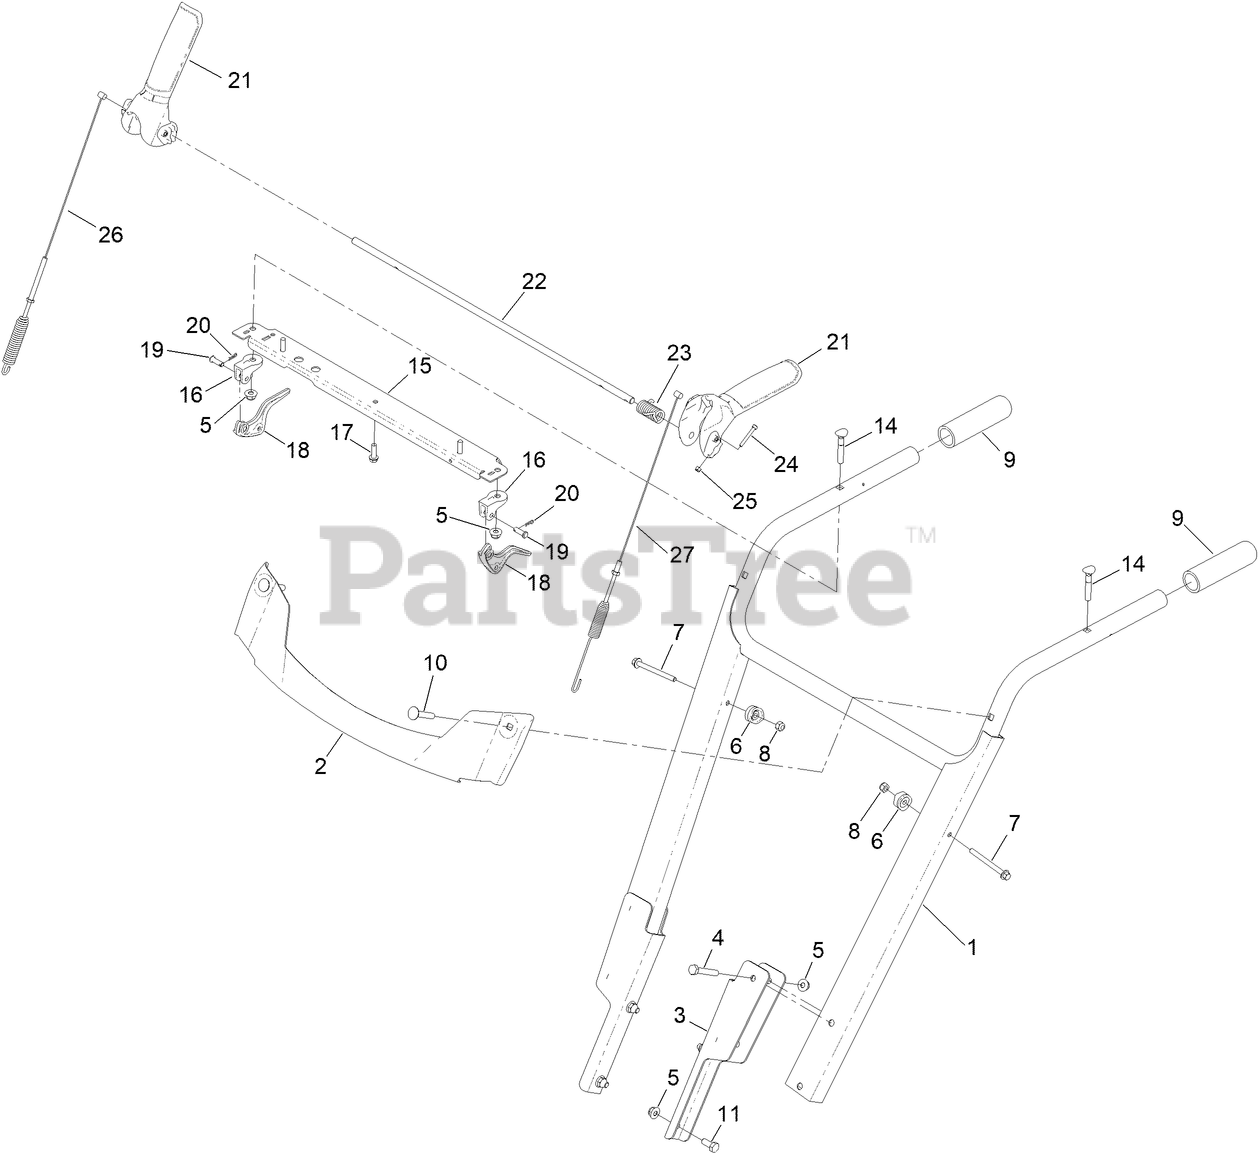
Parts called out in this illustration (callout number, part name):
1	HD HANDLE ASM
2	TRIM-METAL, HD
3	BRACKET-HANDLE, LOWER
4	SCREW-HH
5	NUT-HF
6	CLAMP-CABLE
7	SCREW-HHF
8	NUT-HEX
9	GRIP-HANDLE
10	BOLT-CARR
11	SCREW-HH
14	SCREW-HANDLE
15	BRACE-CONSOLE
16	MOUNT-LEVER, CLUTCH
17	SCREW-PLASTITE, HWH
18	LEVER-CLUTCH
19	PIN-CLEVIS
20	PIN-HAIR
21	LEVER-CONTROL
22	ROD-LOCKOUT
23	SPRING-TORSION, HANDLE RETURN
24	SCREW-HSH
25	NUT-LOCK
26	CABLE-AUGER
27	CABLE-TRACTION
